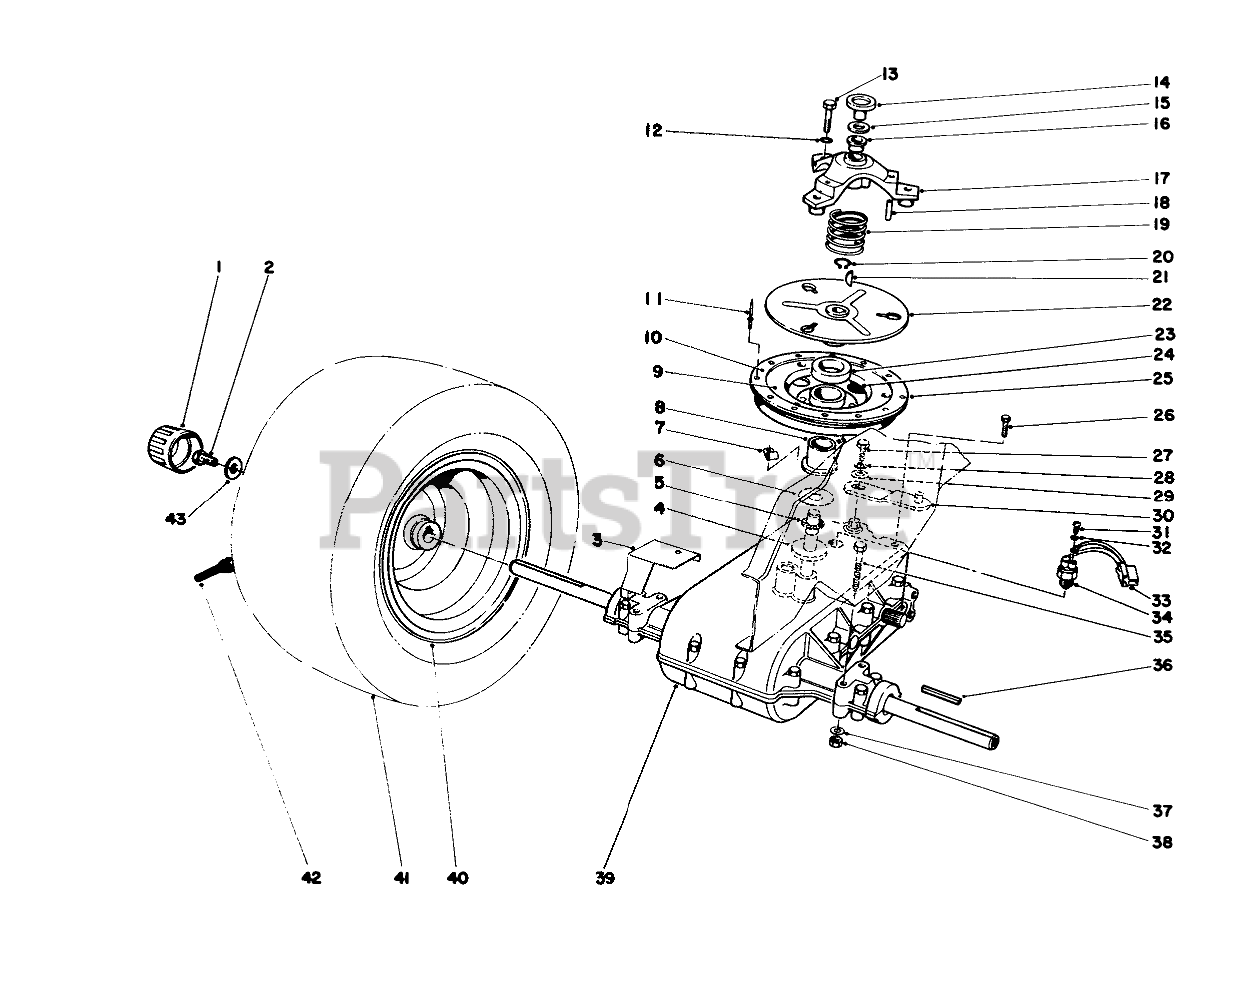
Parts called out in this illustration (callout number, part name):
1	CAP-HUB
2	CAPSCREW 3/8 16 3/4
3	GRASS SHIELD B
4	SPACER
5	NEEDLE BRG
6	THRUST WASHER
7	Clamp (Incl. with Main Wire Harness)
9	CLUTCH PAD
10	RETAINER RING R
11	RIVET
12	WASHER-LOCK
13	SCREW-HH
14	CLUTCH CAP
15	THRUST RACE
16	BUSHING-FLANGE
17	Clutch Cover Assembly (Incl. Ref. #16 & 18)
18	NEEDLE BRG
19	COMPRESSION SPRING
20	RING-SNAP, EXTERNAL
21	KEY-WOODRUFF
22	Clutch Plate
23	WASHER FELT
25	Sheave Assembly (Incl. Ref. #8-11)
26	SCREW-HWHTF
27	SCREW-HH
28	WASHER-LOCK
29	WASHER-FLAT
30	SHIFT LEVER WA B
31	SCREW
32	WASHER-LOCK/INT
33	WIRE HARNESS
34	NEUTRAL SWITCH
35	SCREW-HH
37	WASHER-PLAIN
38	NUT-LOCK, NI
39	TRANSAXLE
40	WHEEL ASM
42	STEM-VALVE
43	SPACER-WHEEL
